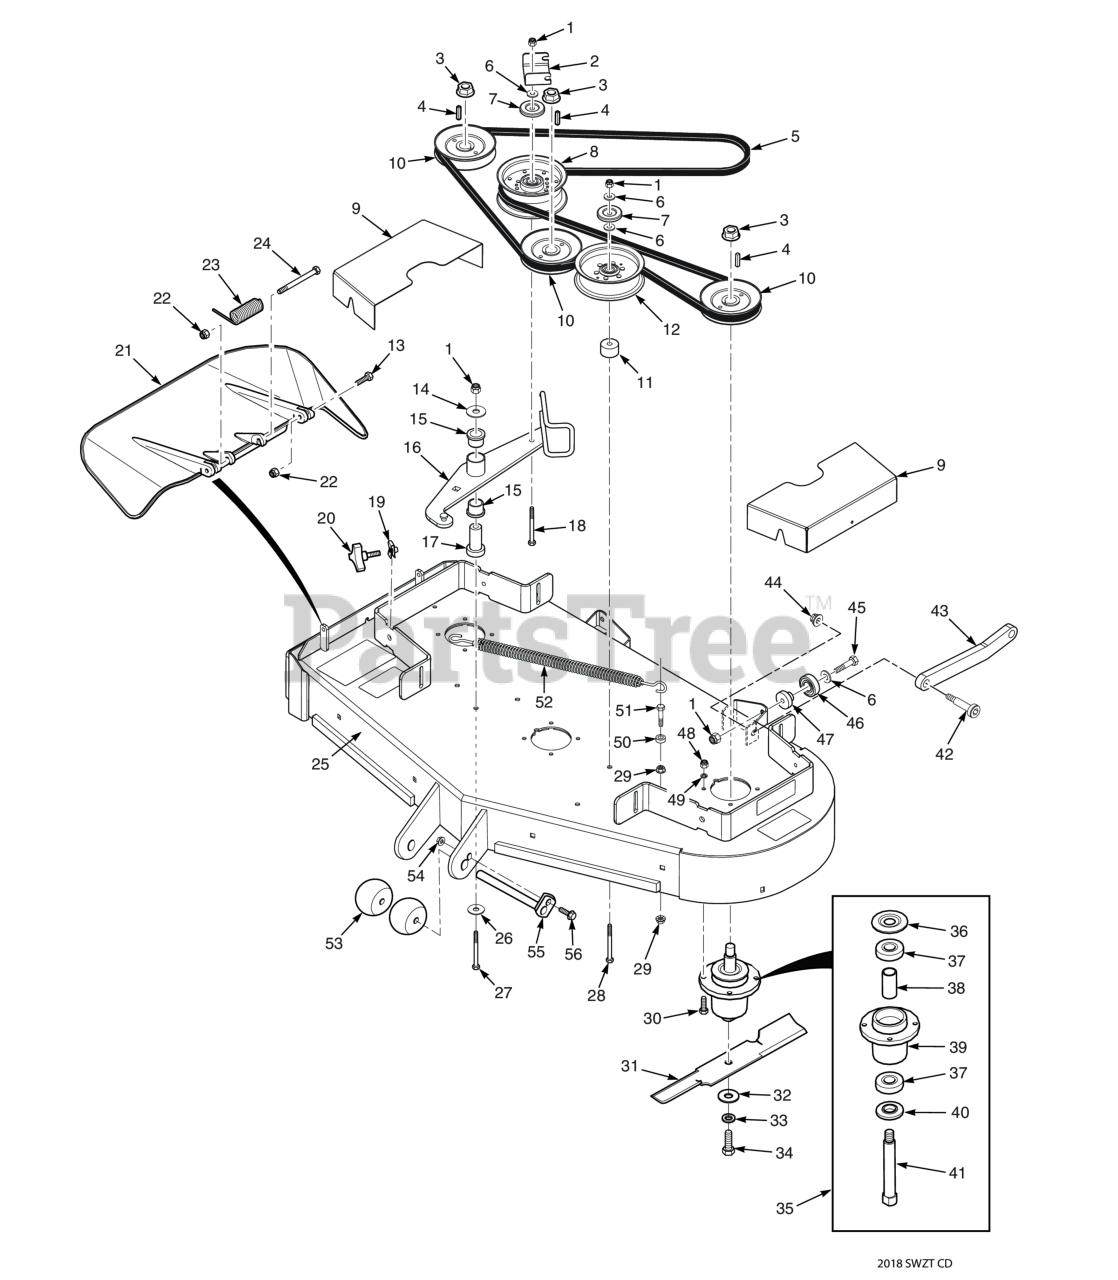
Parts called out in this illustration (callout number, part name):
1	HEX NUT, ELASTIC STOP LOCK, 3/8-16
2	Bracket, Belt Guide
3	Nut, 3/4-16 Spriral Lock
4	Key, 1/4 x 1/4 x 1.25" Pulley Mtg.
5	Belt, Cutter Deck
6	Flatwasher, 3/8 (.391 x .938 x .105 HD) Grade 8
7	Quick Pin, 5/16" Dia.
8	Pulley, Idler 5" Dia.
9	Belt Cover
10	Pulley, 5.13" OD - 25mm Bore
11	Spacer, Idler Pulley
12	Pulley, 5" Idler
13	Bolt, Hex Head 5/16-18 x 1-1/2" - Front
14	Flatwasher, 3/8-.406 x 1-1-1/2 x 7 Gauge
15	Bearing, Plastic
16	Idler Arm Assembly
17	Pivot, Idler
18	Capscrew, Hex Head 3/8-16 x 3.25"
19	U-Nut, 3/8-16
20	Knob, w/stud 3/8-16 x 1-1/4"
21	Discharge Chute Assy. SFZ48
22	HEX NUT, ELASTIC STOP LOCK, 5/16-18
23	Spring, Discharge Chute
24	Bolt, 5/16-18 x 4-3/4" Hex Head
25	Cutter Deck w/Decals, SWZT48H
26	Flatwasher, 3/8-.406 x 2.25" x .1875
27	Capscrew, Hex Head 3/8-16 x 3-3/4"
28	Bolt, Hex Head, 3/8-16 x 3-1/2"
29	NUT, 3/8-16 SERRATED FLANGE HEX HEAD
30	Bolt, Hex Head 5/16-18 x 1-1/2" Grade 8
31	Cutter Blade, 16-1/2" (48V)
32	Flatwasher, 5/8-.688 x 1-3/4 x .134 HD
33	Lockwasher, 5/8" Spring
34	Bolt, Hex Head 5/8-11 x 1-1/2"
35	Spindle Assembly
36	Debris Shield
37	Bearing
38	Spacer, Bearing
39	Spindle Housing Assembly
40	Protector, Bearing
41	Shaft, Spindle
42	Bolt, Shoulder 1/2 x 3/8-16 x 2-3/4"
43	Pusharm
44	Nut, Flange Elastic Stop Nut, 3/8-16
45	Bolt, Hex Head 3/8-16 x 1-3/4" (Kohler EFI)
46	Bearing
47	Spacer, Bearing
48	Lock Nut, 5/16-18 Elastic Stop Grade 8
49	Lockwasher, 5/16 (.317 x .586 x .078) Helical Spring
50	SPACER, IDLER
51	Bolt, Hex Head 3/8-16 x 1-1/2" Grade 8 Black
52	Spring, Cutter Deck Idler
53	Wheel, Anti-Scalp
54	Nut, Serrated Flange 5/16-18 (Right Front Engine Mounting, Briggs and Kohler Only)
55	Shaft Weldment, Guide Roller
56	Bolt, Heax Head 5/16-18 x 1" (48V / 52V)
